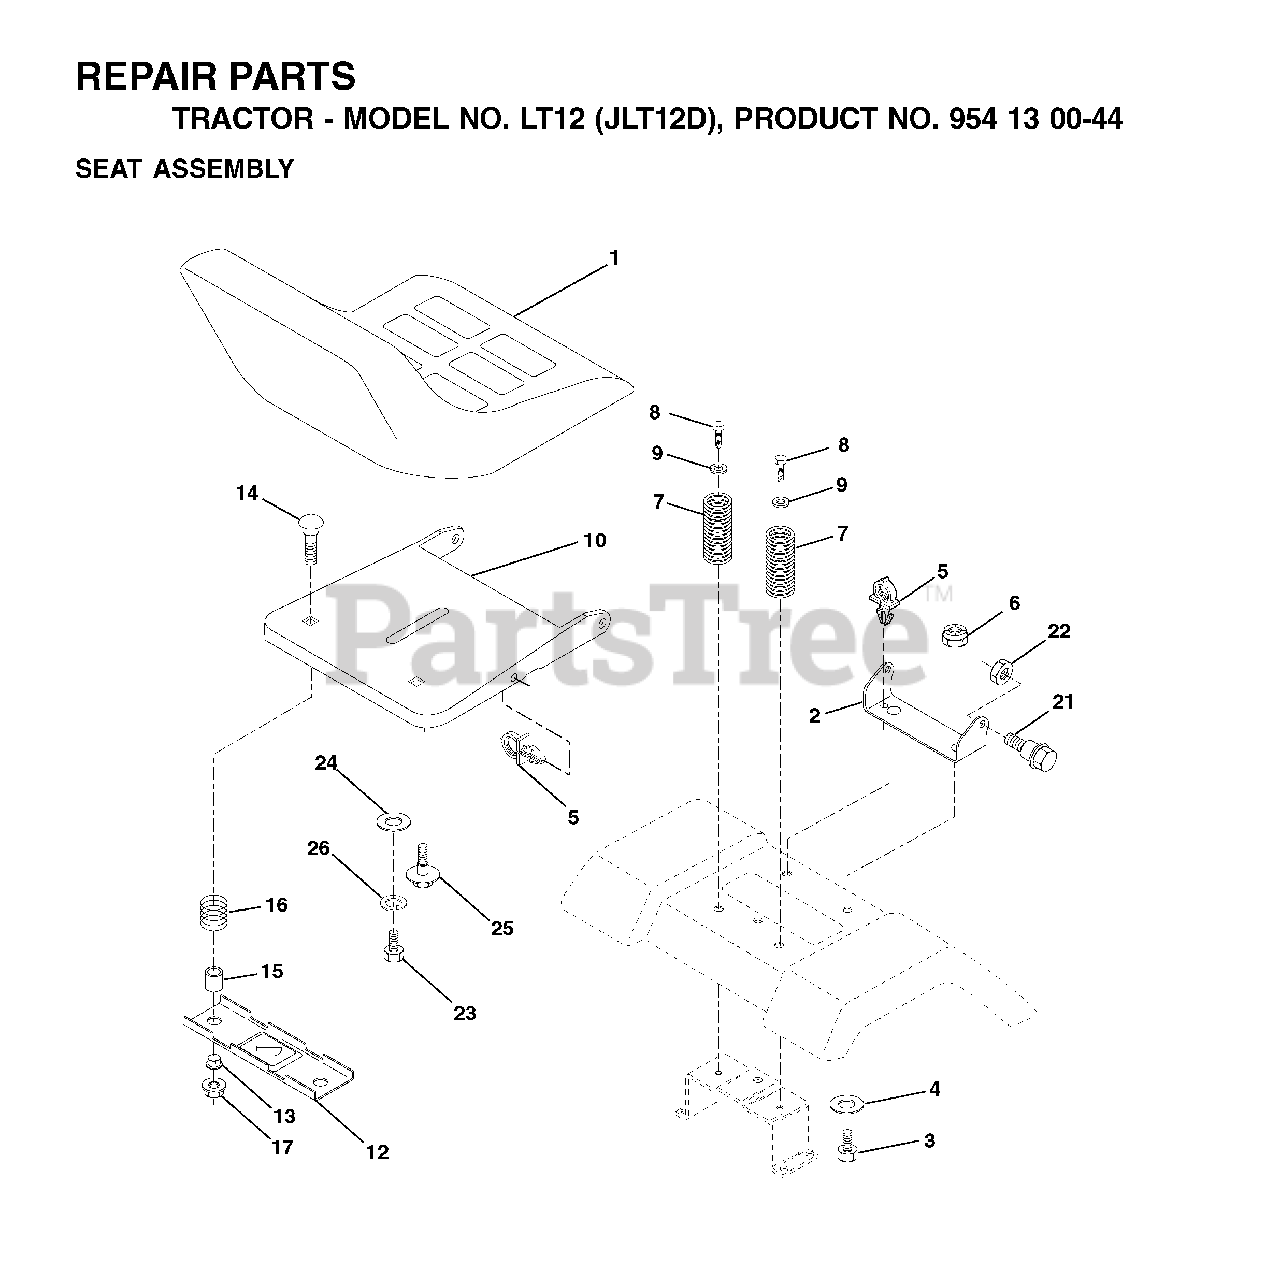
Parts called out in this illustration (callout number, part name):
1	SEAT
2	SEAT PIVOT BRKT
4	WASHER PM
5	PUSH CLIP
6	NUT
7	SPRING COMPRESSION
8	SCREW 3/8-16X1
9	WASHER
10	PAN, SEAT
12	BRKT SWITCH
14	BOLT.ROUND.HEAD.SQUARE.NECK
15	SPACER SPLIT 28X.96
17	NUT T
21	BOLT.SHOULDER.5/16-18
22	NUT.71038.31-18.HEX.NYLOCK
23	BOLT.HEX.BLACK
25	BOLT,SHOULD
26	LOCKWASHER
